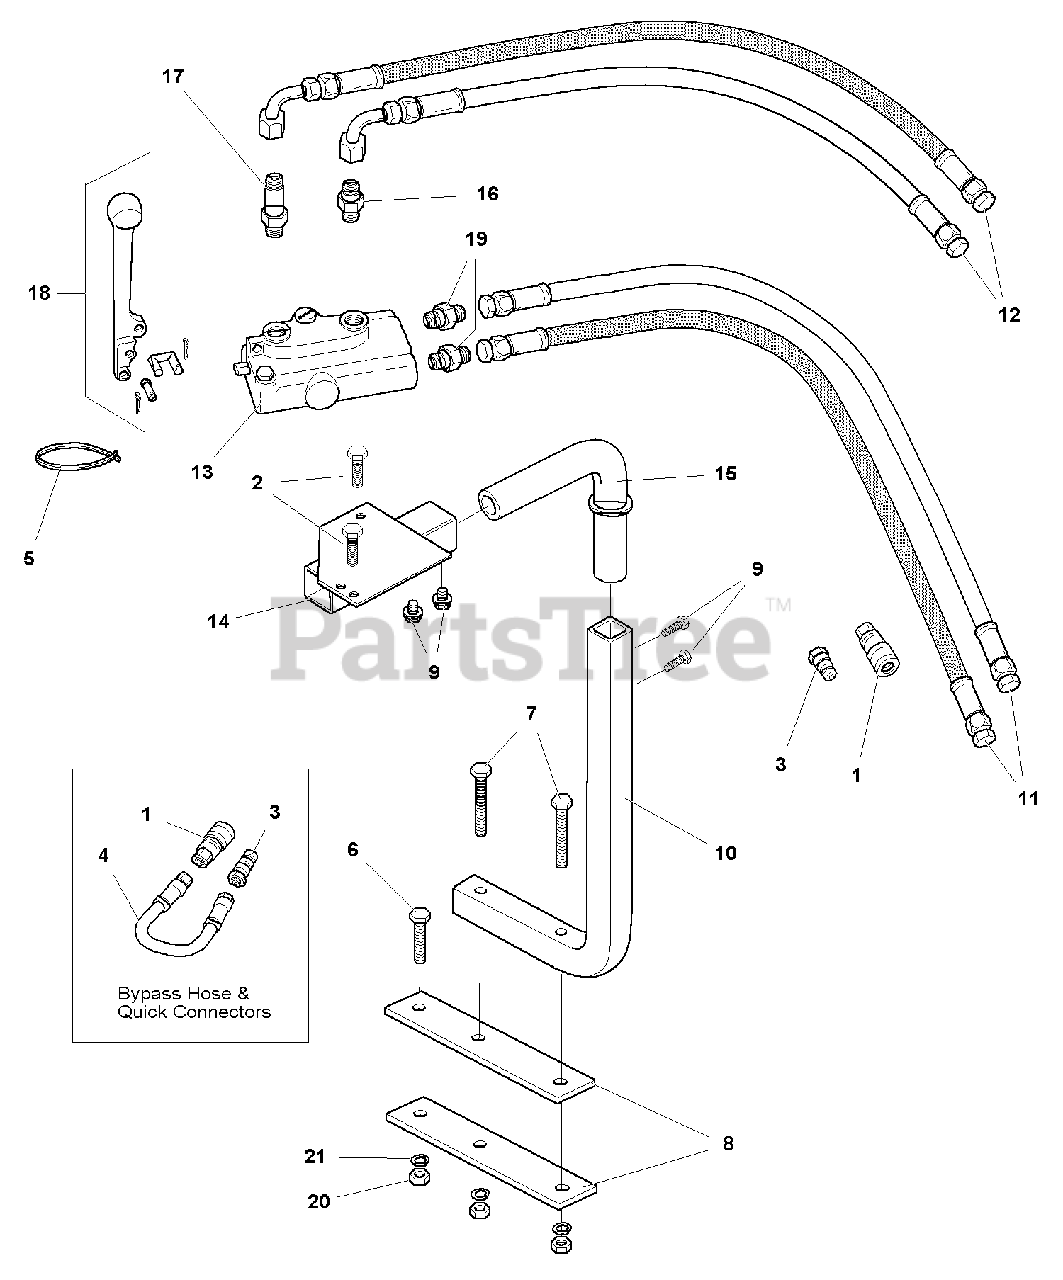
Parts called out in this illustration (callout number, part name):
1	QUICK CONNECTOR, Female Nose Piece Assembly
2	CAPSCREW, Hex Washer Head, Taptite, 1/4-20 X 1-3/4
3	QUICK CONNECTOR, Male Nose Piece Assembly
4	HOSE, Hydraulic, 1/2" x 11"
5	TIE, Self-Locking
6	CAPSCREW, Hex Head, 1/2-13 X 3-1/2
7	CAPSCREW, Hex Head, 1/2-13 x 5, Gr 8
8	PLATE, Clamp, 5/16
9	CAPSCREW, Hex Head, 5/16-18 X 3/4
10	TOWER ASSEMBLY
11	HOSE, Hydraulic, 23/32" x 40"
12	HOSE, Hydraulic, 1/2" x 75"
13	CONTROL VALVE, Single Spool (From Tractor)
14	PLATE ASSEMBLY, Control Valve Mounting
15	TUBE ASSEMBLY, Control Tower Pivot
16	FITTING, Tube, Male, Short
17	FITTING, Tube, Male, Tall
18	KIT, Control Lever & Pin
19	FITTING, Tube, Male
20	NUT, Hex, 1/2-13
21	WASHER, Lock, 1/2
